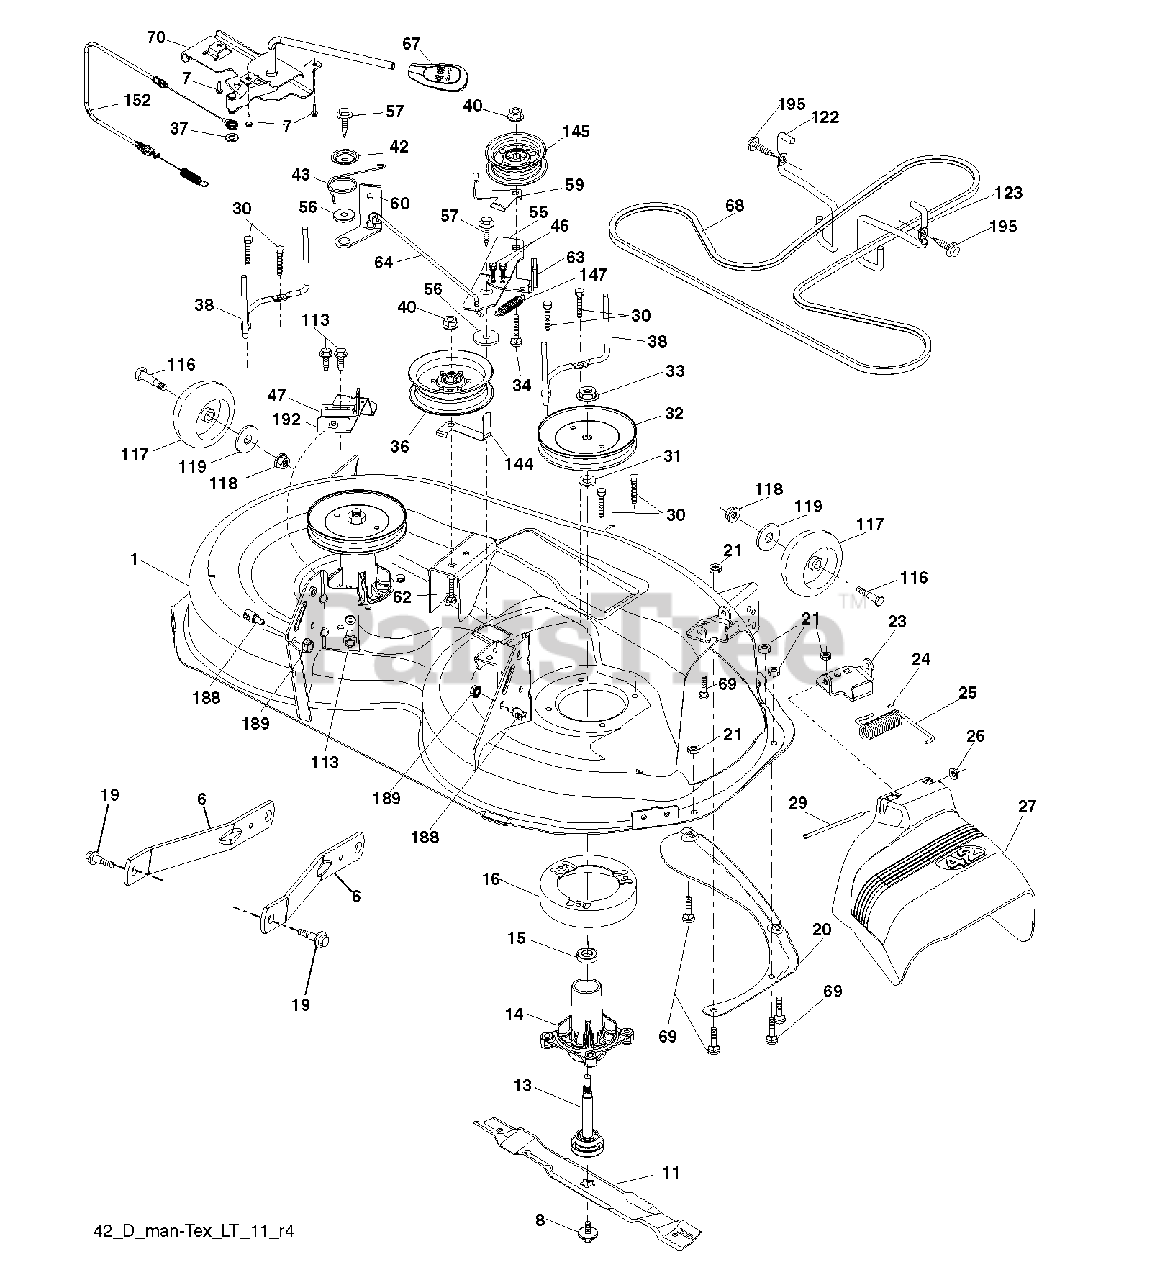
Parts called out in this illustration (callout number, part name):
1	DECK.WELDMENT.42"
6	ARM.SUSPENSION.MOWER.R
7	SCREW
8	BOLT.WASHER.ASM.7/16-2
11	42" HI-LIFT BLADE
13	SHAFT.ASM.MDRL.N/GREASE.38
14	HOUSING MANDREL
16	STRIPPER, MWR ROUND
19	BOLT.SHOULDER
20	BAFFLE.VORTEX
21	LOCKNUT
23	BRKT.DEFLECTOR.38"2005+
24	CAP-SLEEVE LT
25	SPRING.TORSION.DEFLECT
26	NUT PUSH M
27	SHIELD.DEFLECTOR.MOWER.42"BLAC
29	ROD.HINGE
30	SCREW, WASHER HEAD
31	WASHER.SPACER.MANDREL
32	PULLEY.MANDREL.5.438.PD
33	NUT.FLANGE.LOCK.TOP
34	BOLT.3/8-16X1.50
36	PULLEY.IDLER.2006
38	KEEPER.BELT.LH.MANDREL
40	NUT LOCK FLG 3/8-16 UNC
42	SPRING.TORSION.BRAKE
43	SRPING.TORSION.RETAINE
46	SCREW.1/4-20X5/8
47	BRKT.CLUTCH.CABLE
55	IDLER.ARM
56	SPACER.RETAINER
57	SCREW 3/8-16X1
59	GUARD, BELT
60	ARM BRAKE MOWER
62	BOLT
63	ARM BRAKE MOWER
64	LINK BRAKE
67	HANDLE.CLUTCH.CABLE.LT
68	BELT.DRIVE.MOWER.TEX.42"
69	BOLT
70	CLUTCH.ASM.MANUAL.LT.TEX
113	BOLT.5/16HEX.WHS.HD
117	WHEEL.GAGE.HALF.SPOKED
118	LOCKNUT
119	WASHER
122	KEEPER BELT ENGINE LH
123	KEEPER BELT RH
144	KEEPER.BELT.MOWER
145	PULLEY.IDLER.48"PRIMARY
147	RETURN SPRING
152	CLUTCH CABLE
188	STUD.FASTNER.W/ANTI-ROTATE
189	NUT LOCK HEX FLANGE 5/16-18
192	BRKT.BRAKE.STAND.LH.
195	SCREW, 3/8-16X3/4
